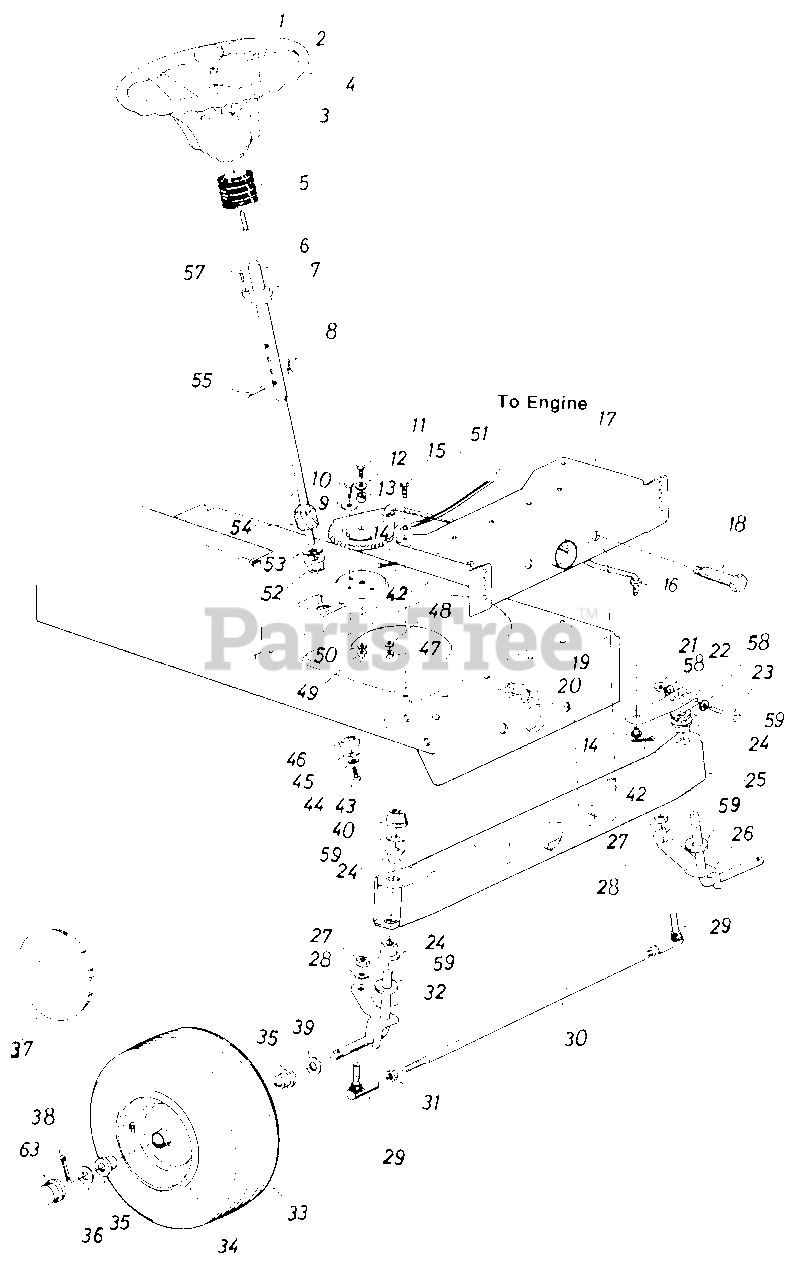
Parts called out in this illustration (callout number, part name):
1	Steering Wheel Cap
2	Hex Nut 5/16-18 Thd.
3	Belleville Wash. .345" I.D.
4	Steering Wheel 12" Dia.
5	Steering Bellow-4.5"
6	Steering Column Ass'y.
7	Flange Bearing .890 I.D. x 1.36 O.D.
8	Internal Cotter Pin 1/4" Dia.
9	Fl-Wash. .438" I.D. x 1.37 O.D.
10	Shoulder Bolt .437" Dia. x .35 Lg. 5/16-18 Thd.
11	Hex Bolt 3/8-24 x 1.0" Lg. (Grade 5)
12	Fl-Wash. .38" I.D. x 1.0" O.D.
13	Spacer.380" I.D. x .625" O.D. x .227
14	Fl-Wash. .56" I.D. x 1.0" O.D.
15	Hex Wash. Hd. AB-Tap Scr. 5/16" x .75" Lg.
16	Steering Drag Link
17	Front Pivot Brkt.
18	Shoulder Bolt .498" Dia. x 2.04 Lg. 3/8-16 Thd.
19	Hex Nut 3/8-16 Thd.
20	L-Wash. 3/8" I.D.
21	Hex Cent. L-Nut 5/16-24 Thd.
22	Steering Arm Front Axle
23	Hex Bolt 5/16-24 x 2.00" Lg. (Grade 5)
24	Hex Flg. Brg. .634 I.D.
26	Front Axle Ass'y.-L.H.
27	Hex Nut 3/8-24 Thd.
28	L-Wash. 3/8" I.D.
29	Ball Joint 3/8-24 Thd.
30	Tie Rod
31	Hex Jam Nut 3/8-24 Thd.
32	Front Axle Ass'y.-R.H.
33	Wheel Ass'y. Comp.
34	Front Wheel Rim Only
35	Bearing
36	Fl-Wash. .635 I.D. x 1.59" O.D.
37	Front Wheel Hub Cap (Chrome)
38	Cotter Pin 118" Dia. x 1.25" Lg.
39	Fl-Wash. .635" I.D. x 1.20" O.D.
40	Push Cap 518" Dia. Rod
42	Cotter Pin 1/8" Dia. x 1.0" Lg.
43	Hex L-Bolt 5/16-18 x .62" Lg.
44	L-Wash. 5/16" I.D.
45	Fl-Wash. .344" I.D. x 1.25" O.D.
46	Spacer (Plastic)
47	Hex Nut 3/8-24 Thd.
48	L-Wash. 3/8" I.D.
49	Hex Nut 5/16-18 Thd.
50	L-Wash. 5/16" I.D.
51	Steering Gear Segment
52	Hex Flg. Brg. .634 I.D.
53	Fl-Wash. (Hardened)
54	Steering Shaft Lower
55	Clevis Pin 1/4" Dia. x 1.00" Lg.
57	Oval Hd. Cr.-Sunk Scr. #10 x 5/8" Lg.
58	Bell-Wash.
59	Fl-Wash. (Hardened)
63	Dust Cap
